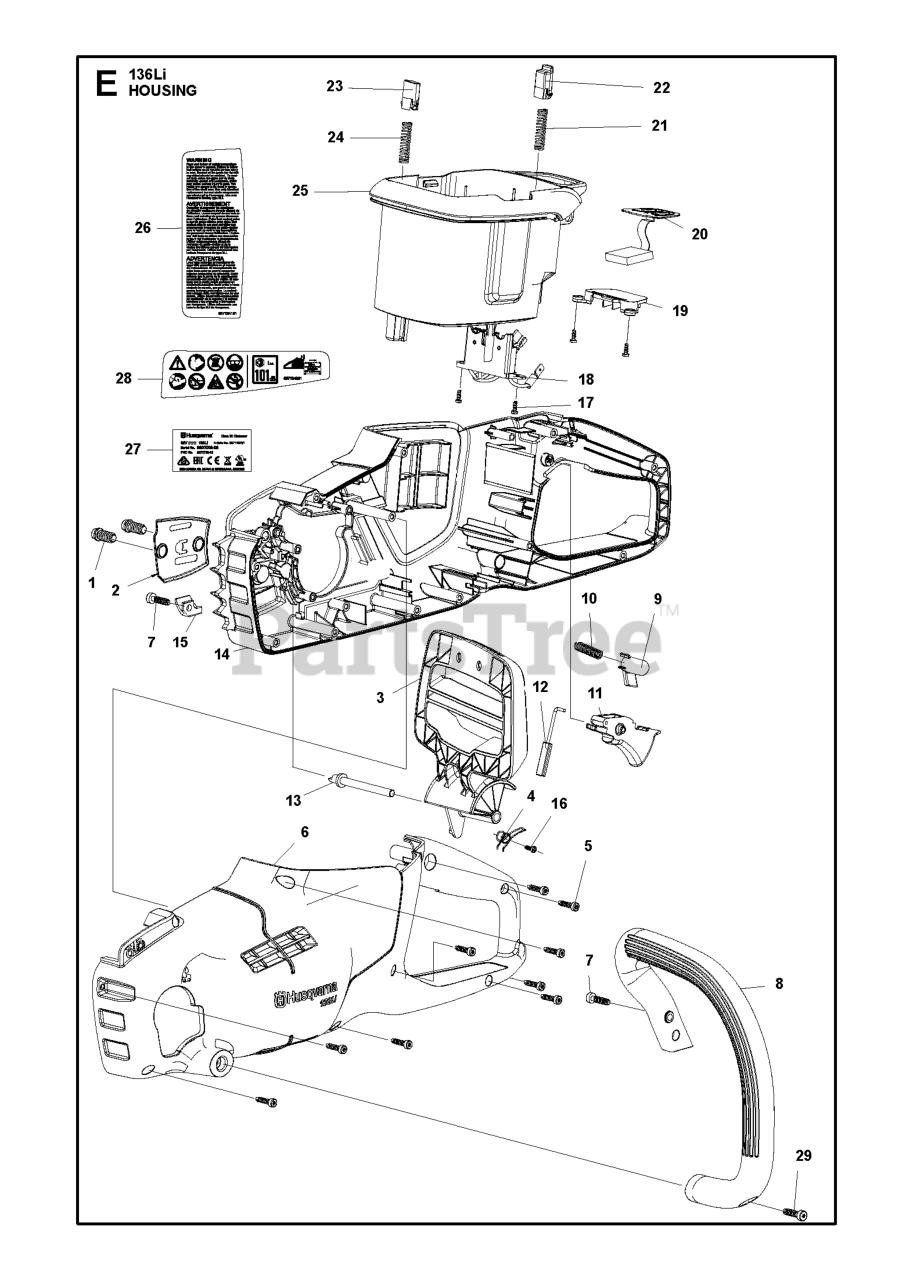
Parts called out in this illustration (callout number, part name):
1	SCREW ST8X16
2	MOUNTING PLATE BAR
3	BRAKE HAND GUARD
4	SPRING BRAKE CUT OFF POWDER
5	SCREW M5X13TOR X MACHINING SCR
7	SCREW
8	FRONT HANDLE
9	BUTTON LOCK OFF
10	SPRING LOCK OFF BUTTON
12	LEVER TRIGGER
13	PIVOT HAND GUARD
15	CHAIN CATCHER
16	SCREW SCREW MT3X10 36V
17	SCREW ST3X8
19	BRACKET KEY PAD
21	SPRING PUSH BUTTON
23	PUSH BUTTON FRONT
24	SPRING PUSH BUTTON
25	BATTERY BOX
26	LABEL WARNING TEXT, US
29	SCREW
